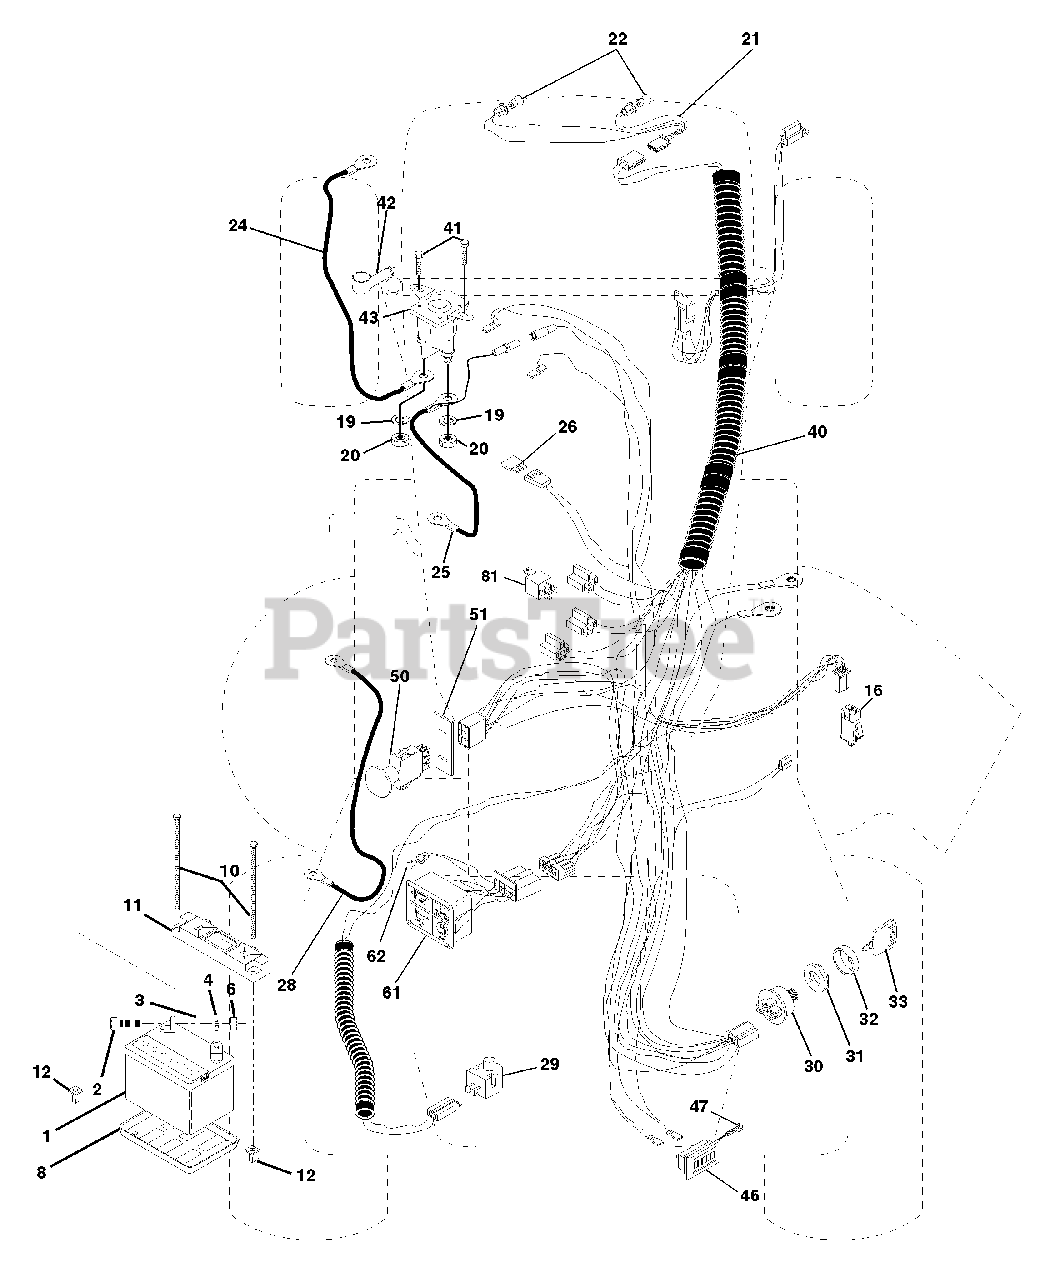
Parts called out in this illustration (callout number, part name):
1	Battery
2	Bolt Hex Head 1/4-20 x 3/4
3	Washer, Lock 1/4
4	Washer 9/32 x 5/8 x 16 Ga
6	Nut Fin Hex 1/4-20
8	Tray, Battery
10	Bolt, Btr Frt 1/4-20 x 7-1/2 Zinc
11	Holddown Battery Front Mount
12	Nut Push Nylon 1/4" Battery Frt.
16	Switch Interlock Push-In
19	Washer, Lock 1/4
20	Nut, Jam Hex 1/4-20
21	Harness Socket Light w/4152J
22	Bulb Light
24	Cable, Starter
25	Cable, Battery
28	Cable, Ground
29	Switch, Plunger
30	Switch, Ign
31	Nut, Ignition Switch
32	Cover Switch Key
40	Harness Ign.
41	Screw 1/4-20 x 1/2
42	Cover, Terminal Red
43	Solenoid
46	Meter Hour
47	Screw #10-24 x 1/2
50	Switch, PTO
51	Ring Retainer PTO
61	Light Pkg Asm
62	Bulb, Light Pkg.
81	Relay Asm.
